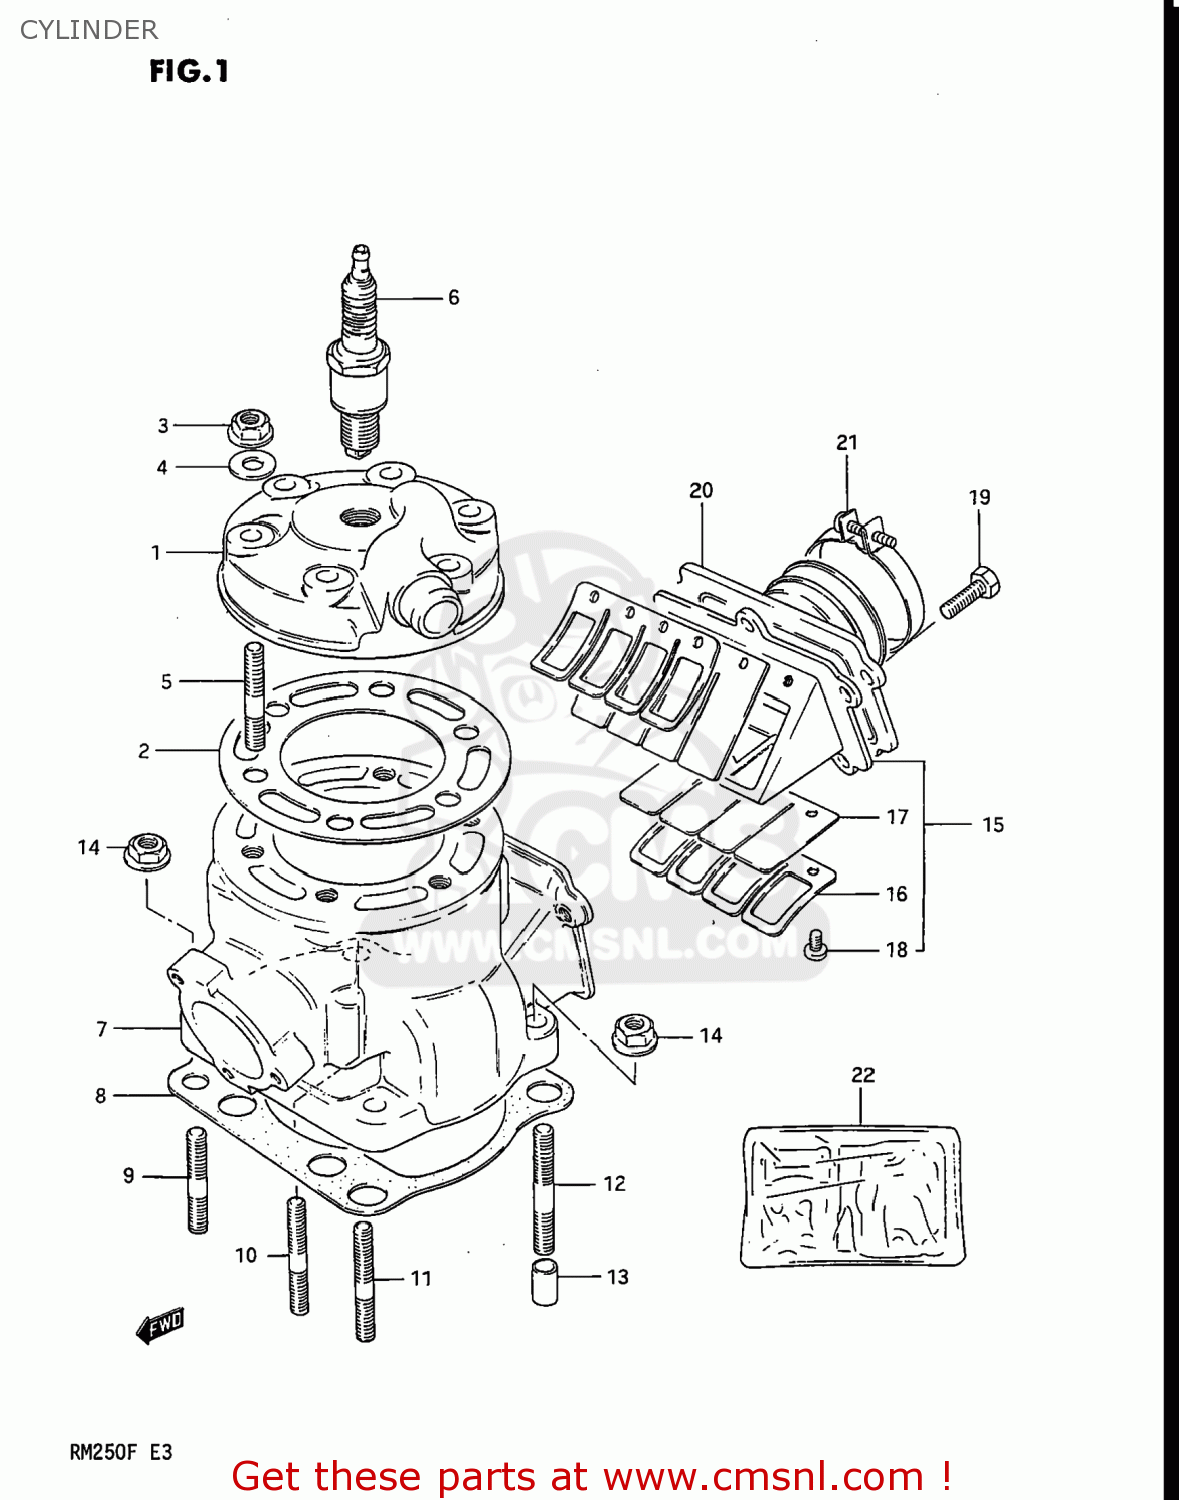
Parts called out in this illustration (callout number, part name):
1	HEAD,CYLINDER
2	GASKET,CYLINDER HEAD
3	NUT 8MM
4	WASHER (8.5X19X2.3)
5	STUD
6	PLUG,SPARK(NGK B-8EN)
7	CYLINDER
8	GASKET,CYLINDER (MCA)
9	BOLT,STUD
10	BOLT,STUD
11	BOLT,STUD
12	BOLT,STUD
13	PIN
14	NUT 8MM
15	VALVE ASSEMBLY,REED
16	STOPPER,REED VALVE
17	VALVE,REED
18	SCREW
19	BOLT
20	PIPE,INTAKE
21	CLAMP
22	GASKET (MCA)
